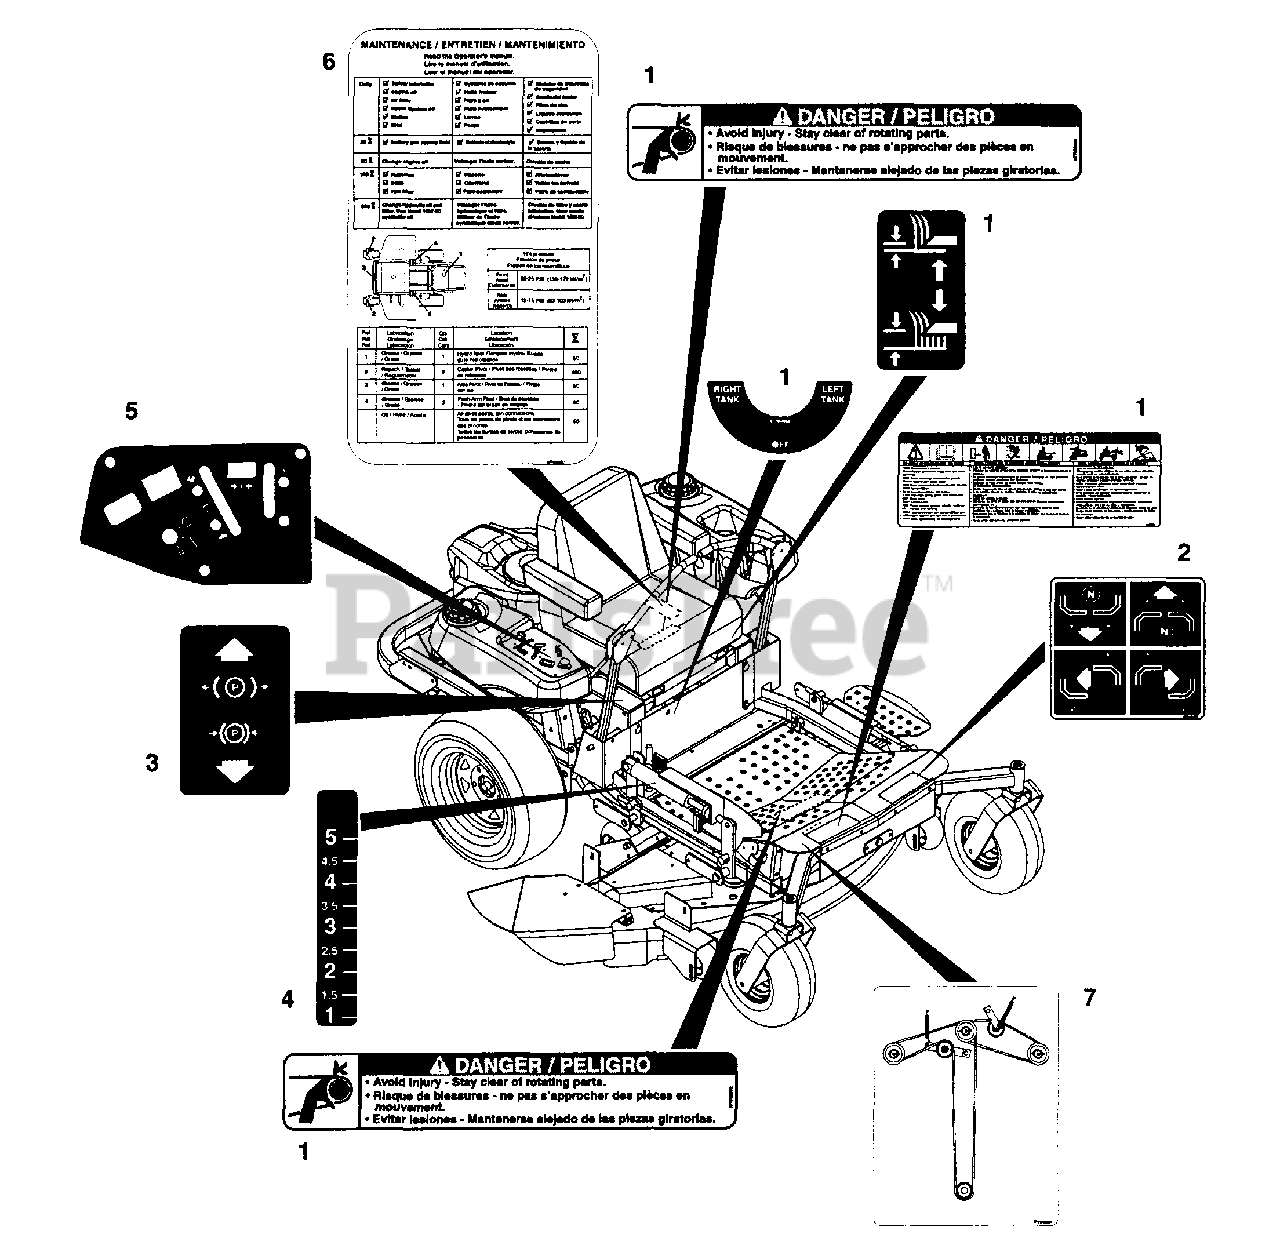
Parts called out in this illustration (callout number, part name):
1	SET, DECAL-COMMON DANGER/FUEL
2	DECAL, INSTRUCTIONAL-STEERING
3	DECAL, PARKING BRAKE LEVER
4	DECAL, HEIGHT OF CUT
5	DECAL, ZOOM/ZT CONTROL PANEL
6	DECAL- SERVICE INSTRUCTIONS
7	DECAL, GRAVELY BELT DIAGRAM
